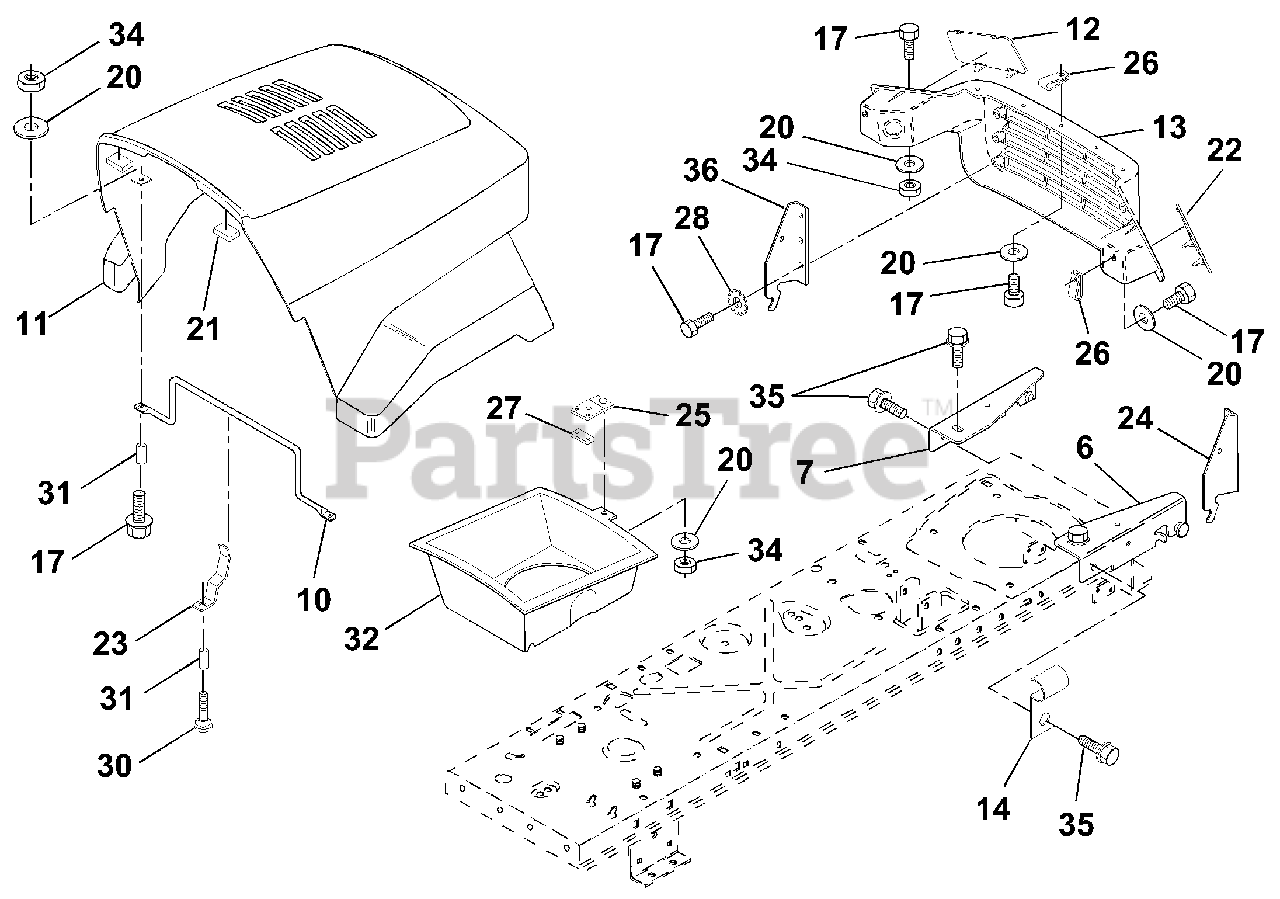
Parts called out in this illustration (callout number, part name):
6	Bracket Asm. Pivot Hood RH
7	Bracket Asm. Pivot Hood LH
10	Brace Hood
13	Grille
14	Clip Line Fuel
17	Bolt Fin Hex 1/4-20 x 5/8
20	Washer 9/32 x 3/4 x 16 Ga.
21	Bumper Hood
23	Latch Hood
24	Bracket Pivot Hood RH
25	Clip Asm. Duct Air
26	Clip Tinnerman
27	Clip Tinnerman
28	Washer Lock Ext Tooth
30	Bolt RDHD Sht Nk 1/4 - 20 x 1-3/8
32	Duct Air Hood
34	Nut Keps 1/4-20
35	Screw Thdrol 5/16-18 x 3/4
36	Bracket Pivot Hood LH
